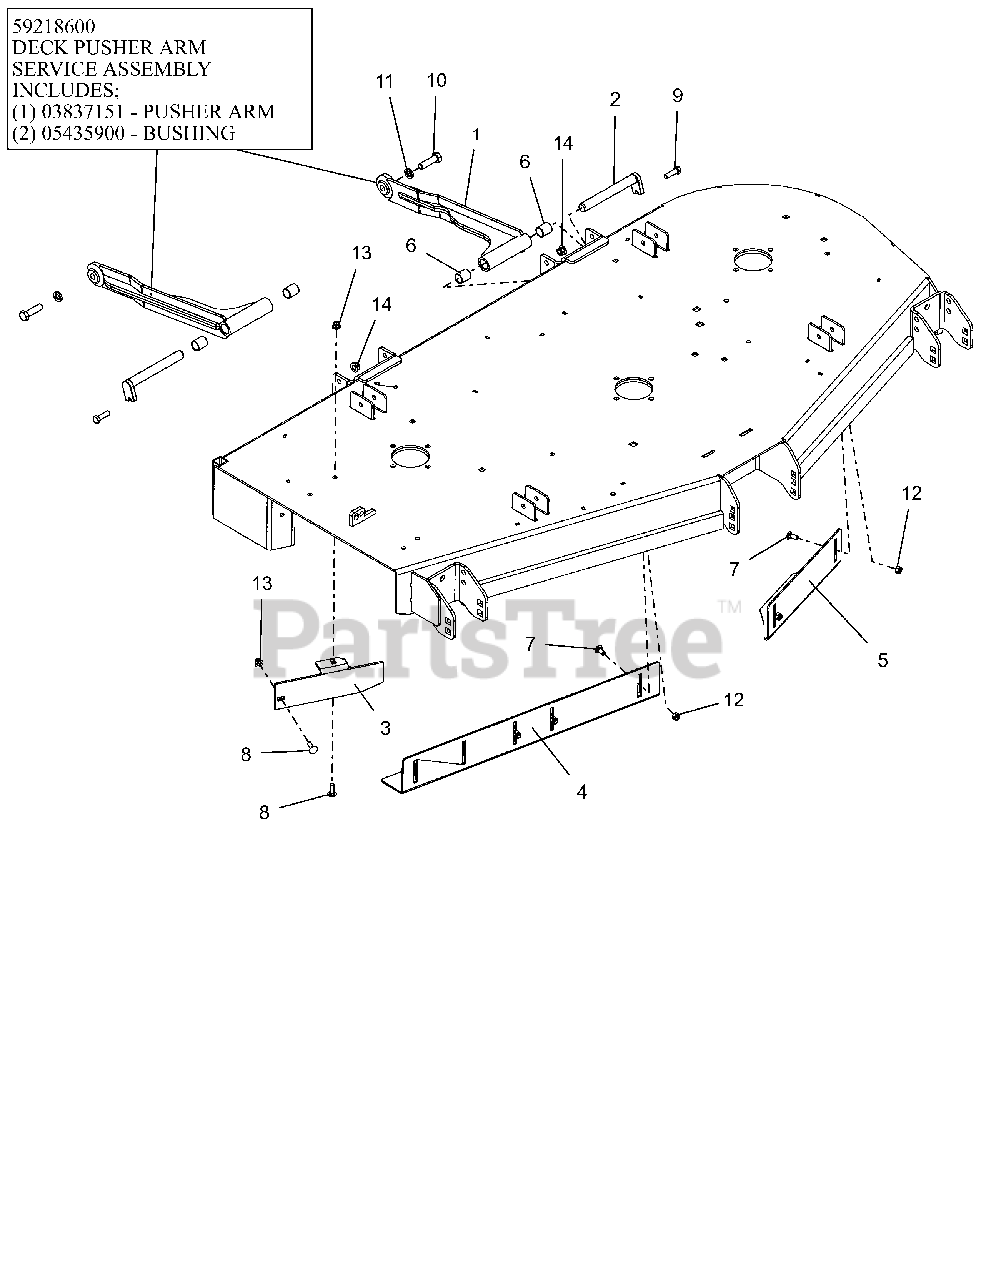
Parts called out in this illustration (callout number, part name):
1	DECK STABILIZER ARM - BLACK
1	DECK STABILIZER ARM W/BUSHINGS
1	BRG, .750 X .875 X 1.000
2	PIN, MOWER MTG
3	60" DISCHARGE BAFFLE - RED
4	60" RH VACUUM BAFFLE - RED
5	60" LH VACUUM BAFFLE - RED
6	BRG, .750 X .875 X 1.000
7	@BLT-RDHDSQNK .31-18X.75 G5YZ
8	@BLT-RDHDSQNK .31-18X1.00 G5YZ
9	@BLT-HEX .38-16X1.25 GR5 YWZC
10	BLT-HEX .50-13X1.75 GR5EP80 YZ
11	@WSHR-LK .50X.125 REG YWZC
12	@NUT-LK-NYL .312-18 YWZC
13	@NUT-LK-NYL-FLG .31-18 YWZC
14	@NUT-LK-NYL-FLG .38-16 YWZC
